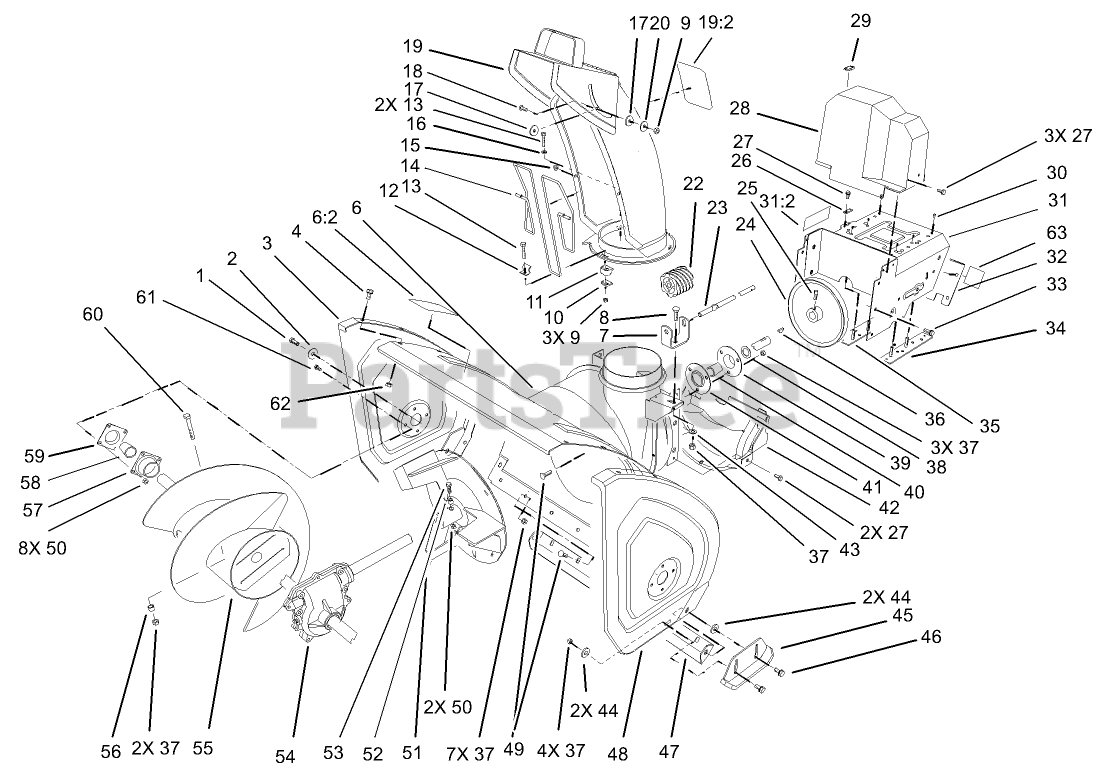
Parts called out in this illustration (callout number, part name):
1	SCREW-HH
2	WASHER
3	PLATE-SIDE, RH
4	SCREW-HHF
6	AUGER HOUSING ASM
7	BRACKET-WORM, CHUTE
8	BOLT-CARR
9	NUT-LOCK, NI
10	PLATE-RETAINER, CHUTE
11	RETAINER-CHUTE
12	CLIP-GUARD, CHUTE
13	SCREW-HSH
14	GUARD-CHUTE
15	NUT-PUSH
16	WASHER-FLAT
17	WASHER-PLASTIC
19:2	DECAL-DANGER
20	WASHER-FLAT
22	GEAR-WORM
23	ROD-CHUTE, LOWER
25	SCREW-SET, SQH
26	RETAINER-CABLE
27	SCREW-HWH
28	COVER-BELT, UPPER
29	COVER-CABLE
30	RIVET-POP
31	ENGINE FRAME ASM
31:2	DECAL-WARNING
32	COVER-FRAME, ENGINE
33	SCREW-HWHTF
34	LH FRAME PLATE ASM
35	RH FRAME PLATE ASM
36	KEY-WOODRUFF
37	NUT-LOCK, NI
38	WASHER-THRUST
39	FLANGE-CUP, BEARING
40	BEARING-BALL
41	FLANGE-CUP, BEARING
42	COVER-BELT, LOWER
43	WASHER-PLAIN
44	WASHER
45	SKID ASM
46	SCREW-HHF
47	BLADE-SCRAPER, 28"
48	PLATE-SIDE, LH
49	SCREW-CARR
50	NUT-LOCK, NI
51	IMPELLER ASM-4 BLADE
52	SPACER
53	SCREW-HHF
54	28IN AUGER GEARCASE ASM
55	AUGER ASM-RH, 28"
56	SPACER-HUB, AUGER
57	BEARING-FLANGE, FRONT
58	BEARING
59	BEARING-FLANGE, REAR
60	SCREW-HH
61	SCREW-HH
62	NUT-LOCK, NI
63	DECAL
